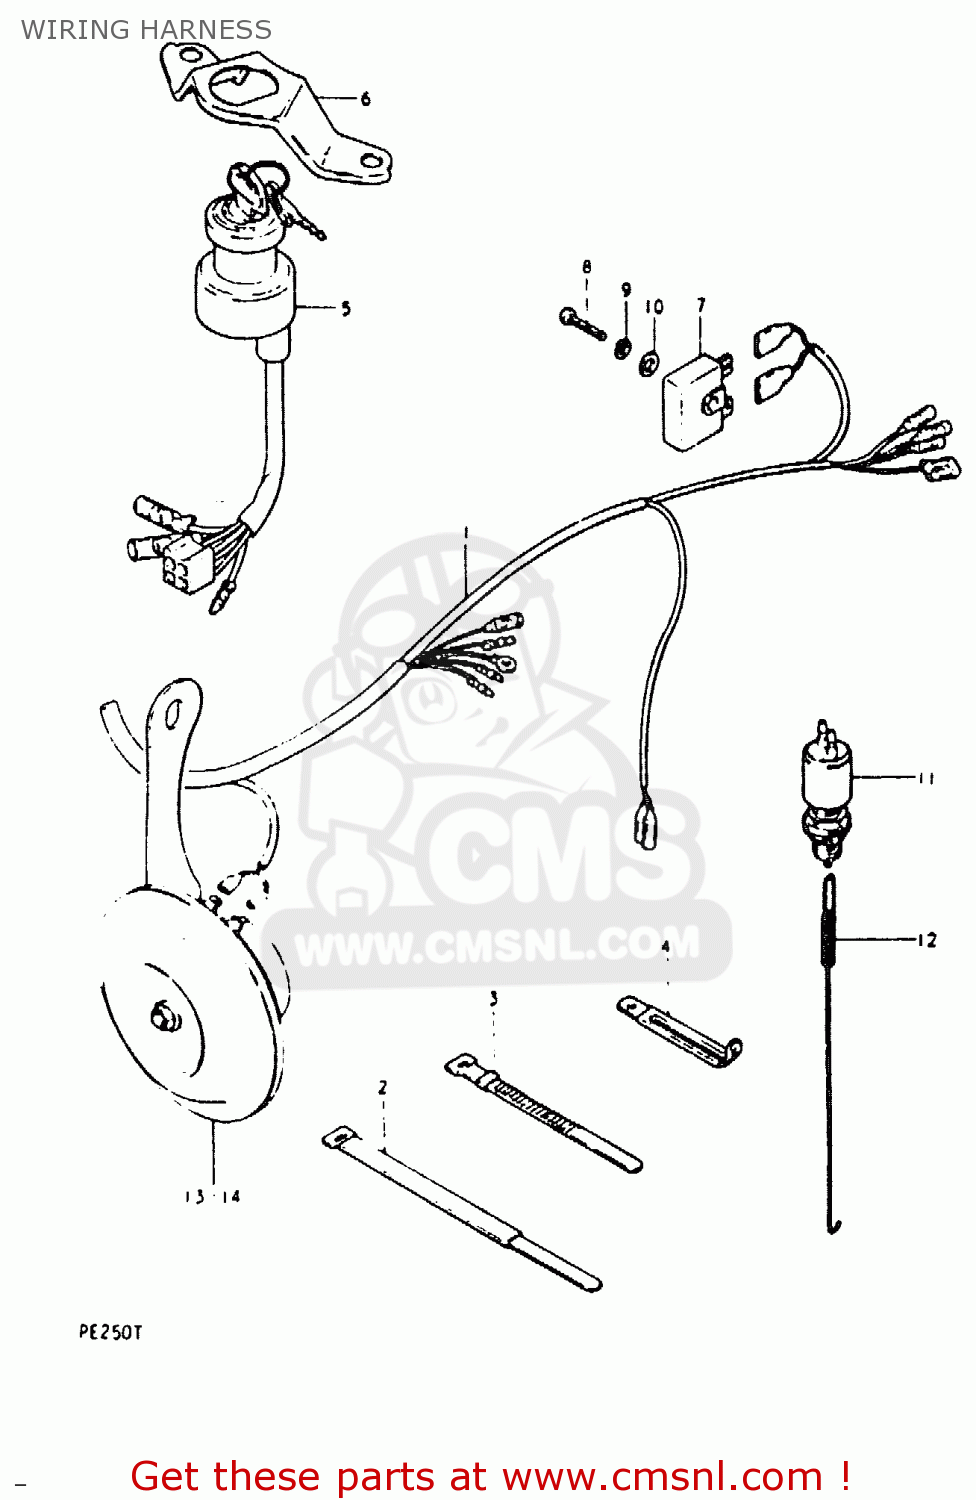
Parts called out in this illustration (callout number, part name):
1	WIRING HARNESS
2	CLAMP
3	CLAMP(L:120)
4	CLAMP
11	SWITCH ASSY,BRAKE LAMP
12	SPRING
13	HORN (WHITE)
